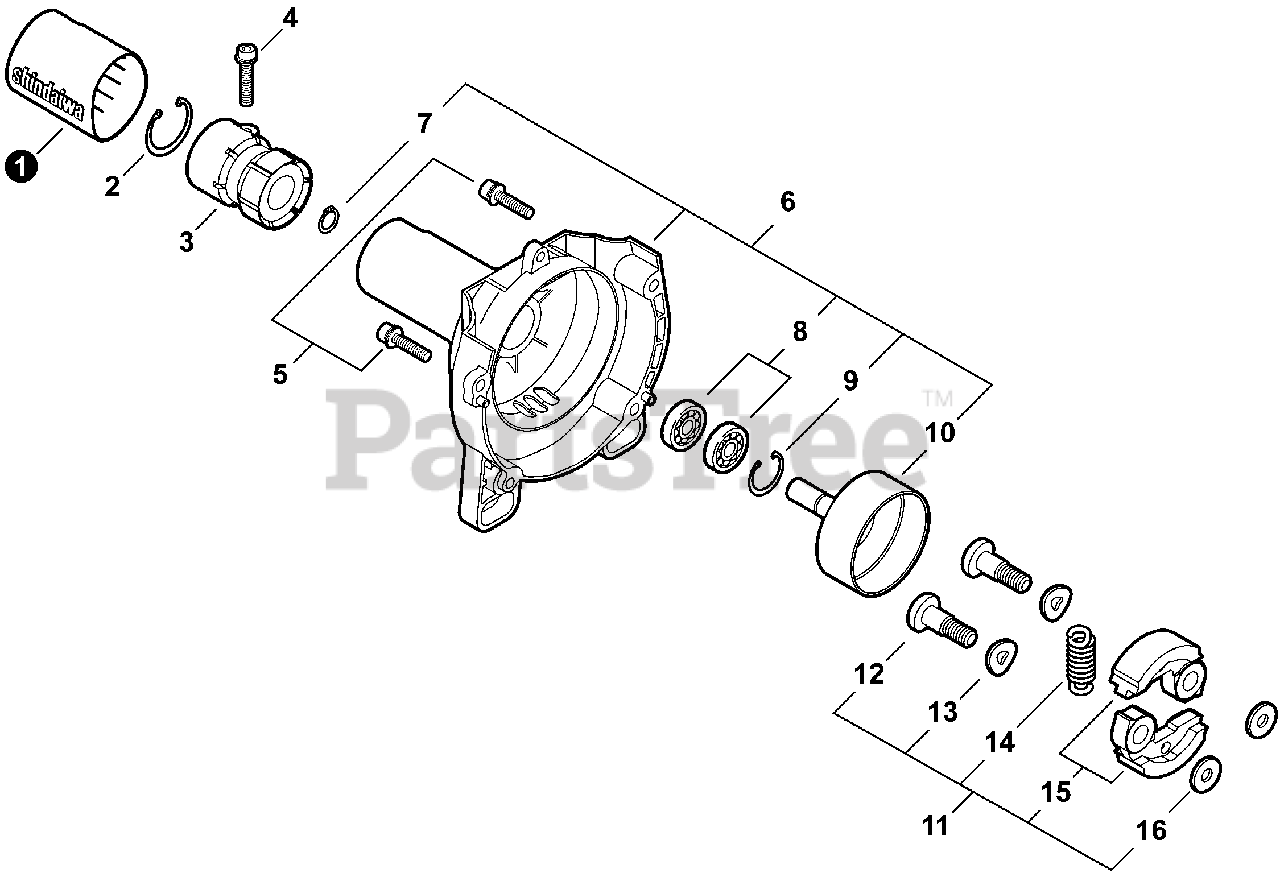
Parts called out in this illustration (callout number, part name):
1	PROTECTOR
2	RING, SNAP Ø40
3	CUSHION, AV
4	BOLT M5×22
5	BOLT 5×18
6	COVER ASSY, FAN
7	E-RING 10
8	BEARING, BALL 6000DDU
9	RING, SNAP 26
10	DRUM, CLUTCH
11	CLUTCH ASSY
12	BOLT, CLUTCH
13	WASHER, SPRING
14	SPRING, CLUTCH
15	SHOE, CLUTCH
16	WASHER 6 MM
